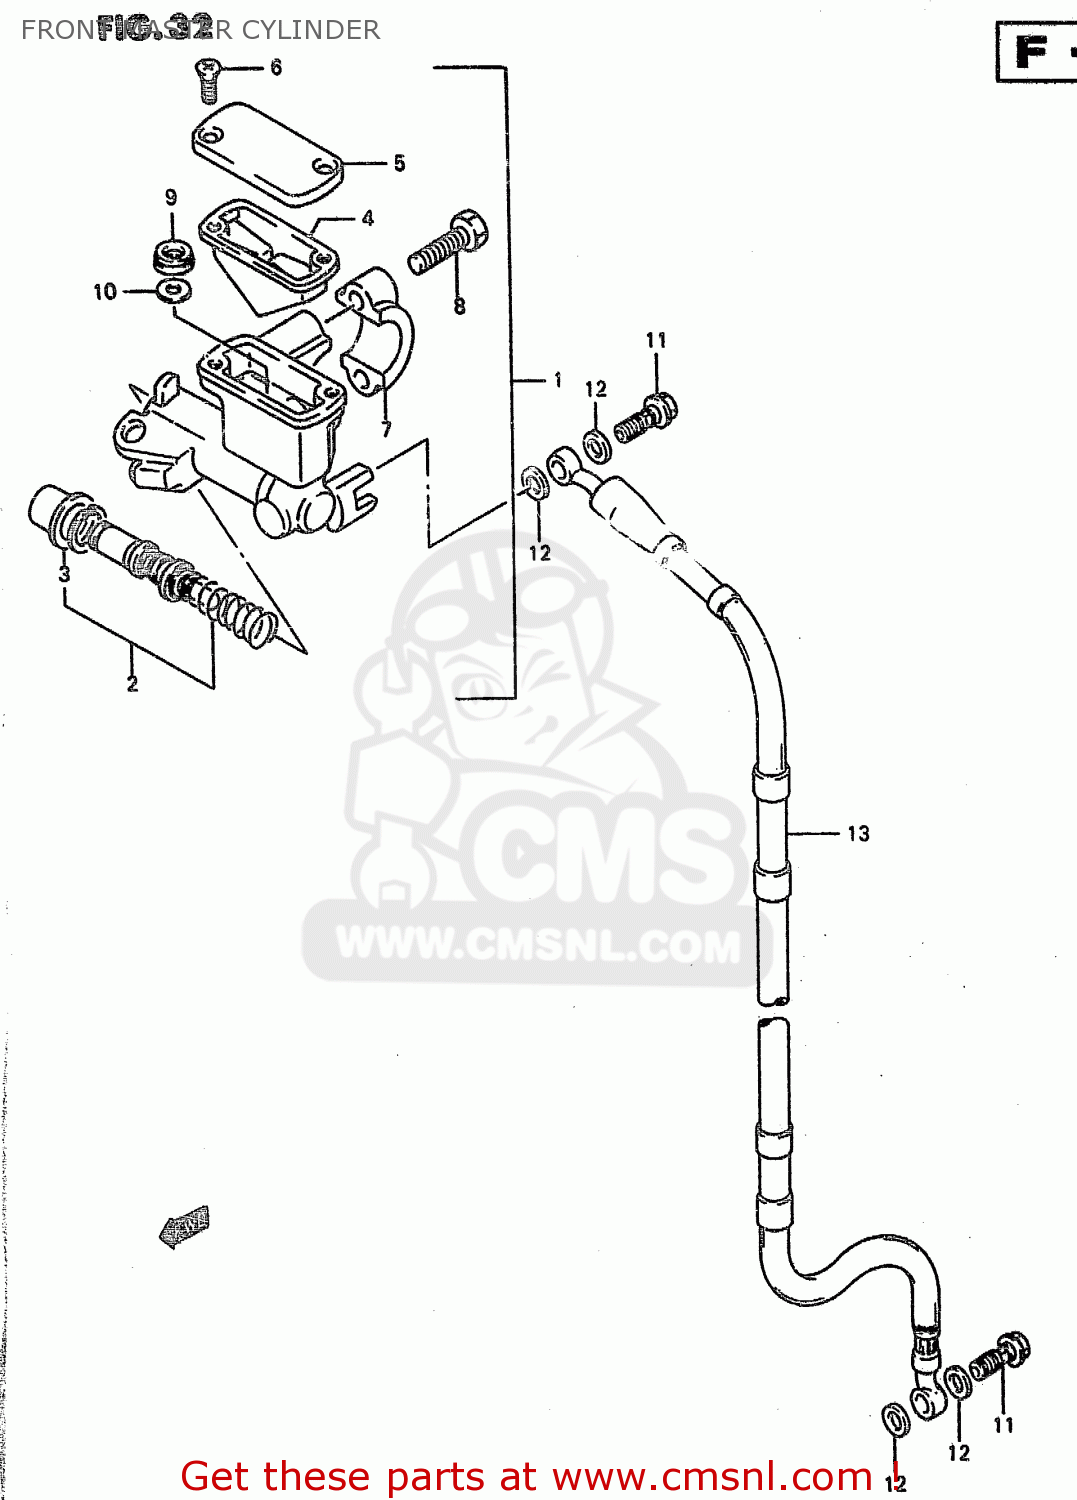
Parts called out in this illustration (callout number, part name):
1	CYLINDER ASSY,FR MASTER
2	PISTON & CUP SET
3	BOOT
4	DIAPHRAGM
5	CAP
6	SCREW
7	HOLDER
8	BOLT
9	SEPARATOR
10	RING
11	BOLT UNION
12	WASHER(10X15X1.5)
13	HOSE COMP,FRONT BRAKE
